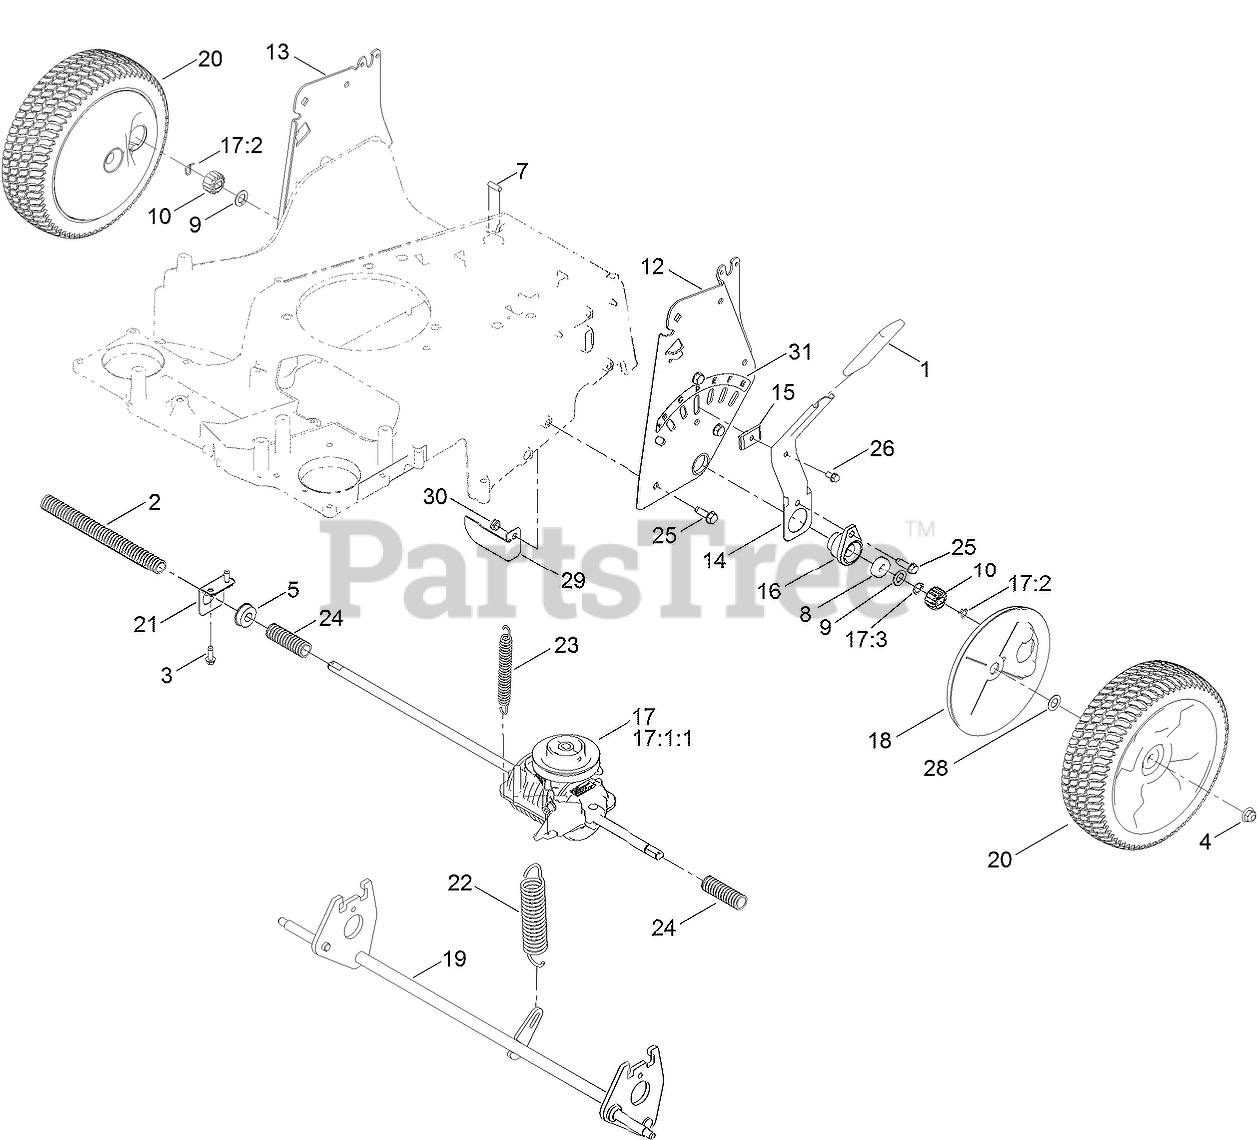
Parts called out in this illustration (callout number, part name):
1	GRIP-LEVER, LIFT
2	CONDUIT-CONVOLUTED
3	SCREW-HWHTF
4	NUT-HF, NI
5	BEARING-BALL
7	PIN-STOP
8	BEARING-BALL
9	WASHER-THRUST
10	GEAR-PINION, 15T
12	PLATE-HOC, LH
13	PLATE-HOC, RH
14	ARM-SPRING, REAR
15	KEY-SPRINGARM
16	RETAINER-BEARING
17	TRANSMISSION KIT
17:1:1	TRANSMISSION PULLEY KIT
17:2	PIN-SNAP
17:3	RING-RETAINING
18	COVER-GEAR
19	AXLE-REAR
20	10 INCH WHEEL GEAR ASM
21	MOUNT-BEARING
22	SPRING-EXTENSION
23	SPRING-EXTENSION
24	CONDUIT-CONVOLUTED
25	SCREW-THD ROLL, HWH
26	SCREW-HWH
28	WASHER-PLAIN
29	BRACKET-STOP
30	NUT-LOCK, NI
31	DECAL-HOC, REAR
